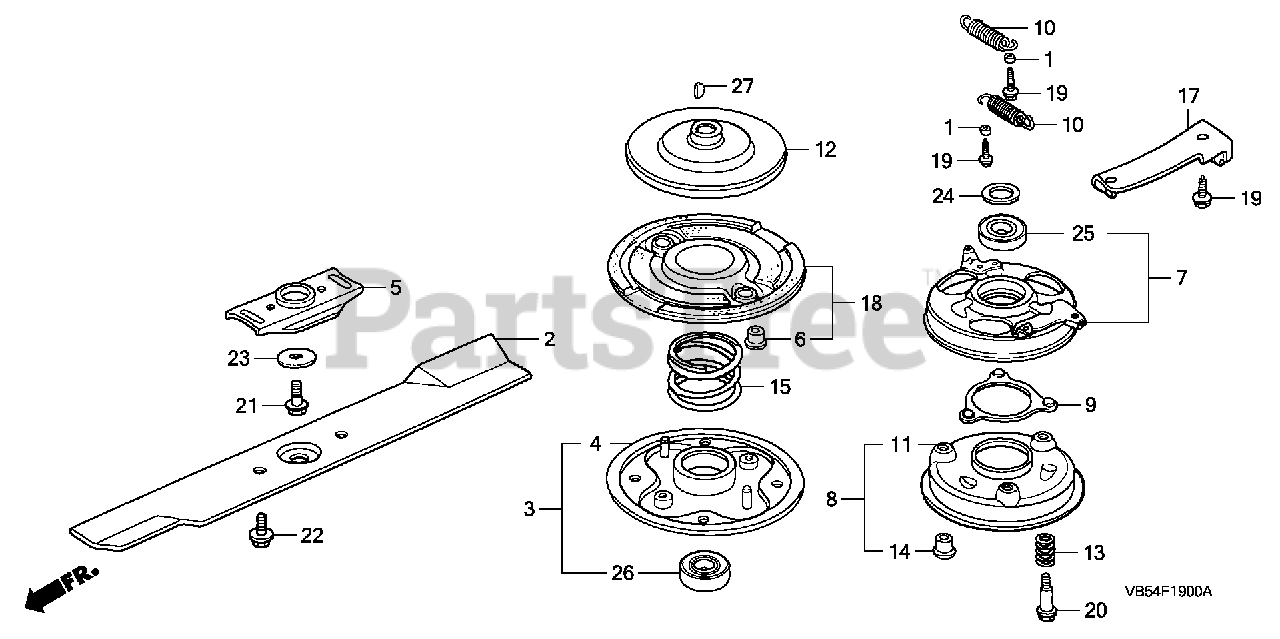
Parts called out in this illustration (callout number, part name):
1	COLLAR, FAN
2	BLADE, ROTARY
2	BLADE, ROTARY (21")
3	HOLDER ASSY., BLADE
4	HOLDER, BLADE
5	HOLDER, BLADE
6	BUSH, BLADE HOLDER
7	PLATE ASSY., BALL CONTROL
9	RETAINER, BALL
10	SPRING, CLUTCH RETURN (63.4MM)
11	DISK, BRAKE
12	DISK, DRIVE
13	SPRING, BRAKE HOLDER
14	BUSH, BRAKE HOLDER
15	SPRING, CLUTCH (38.7MM) (NOT AVAILABLE)
16	PLATE, BALL CONTROL
17	PLATE, CABLE HOOK
18	DISK, DRIVEN
19	BOLT, FLANGE (6X14)
20	BOLT, SPECIAL (6MM)
21	BOLT, HEX. (10X25)
22	BOLT, HEX. (10X20)
23	WASHER (10X30X3.5T)
24	WASHER, THRUST (22X32X3)
25	BEARING, RADIAL BALL (60/22UU)
26	BEARING, RADIAL BALL (6204)
27	KEY, WOODRUFF (16X15)
